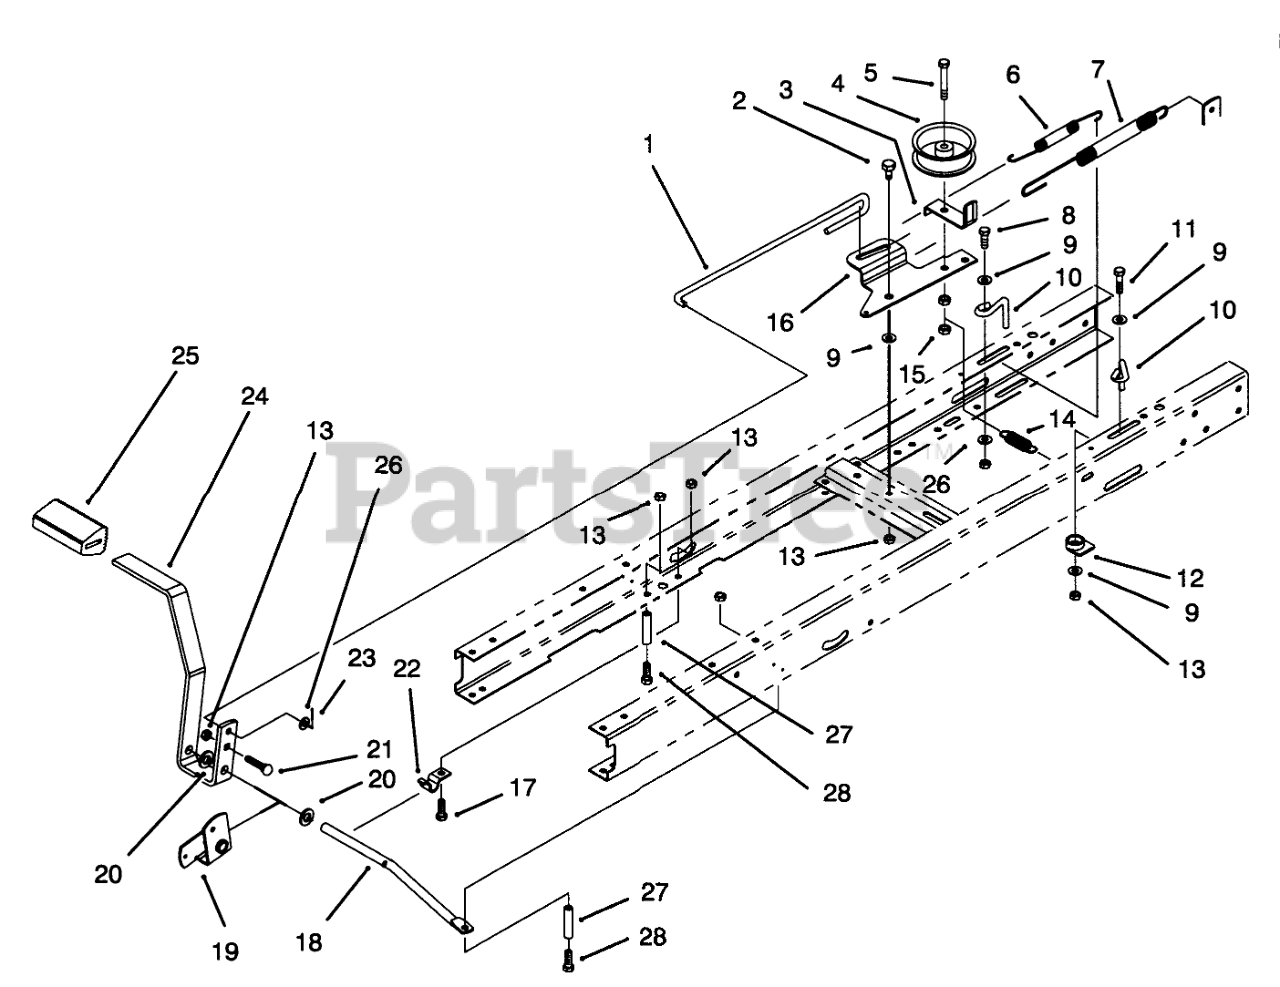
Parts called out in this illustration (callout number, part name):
1	ROD-CLUTCH/BRAKE
2	BOLT-SHOULDER
3	GUIDE-IDLER, BELT
4	Idler Pulley
5	SCREW-HH
6	SPRING-EXTENSION
7	BRAKE SPRING
8	SCREW-HH
9	WASHER-PIVOT
10	TRANS BELT GUIDE
11	SCREW-HH
12	GUIDE-CABLE
13	NUT-LOCK, NI
14	SPRING-EXTENSION
15	NUT-LOCK, NI
16	ARM-IDLER
17	SCREW-HH
18	ROD-PIVOT, PEDAL
19	BelIcrank
20	WASHER-FLAT
21	SCREW-CARR
22	CLAMP-PIVOT, SHIFT
23	PIN-COTTER
24	Pedal-Clutch/Brake
25	PAD-PEDAL
26	WASHER-PLAIN
27	TUBING-SPACER
28	SCREW-HH
